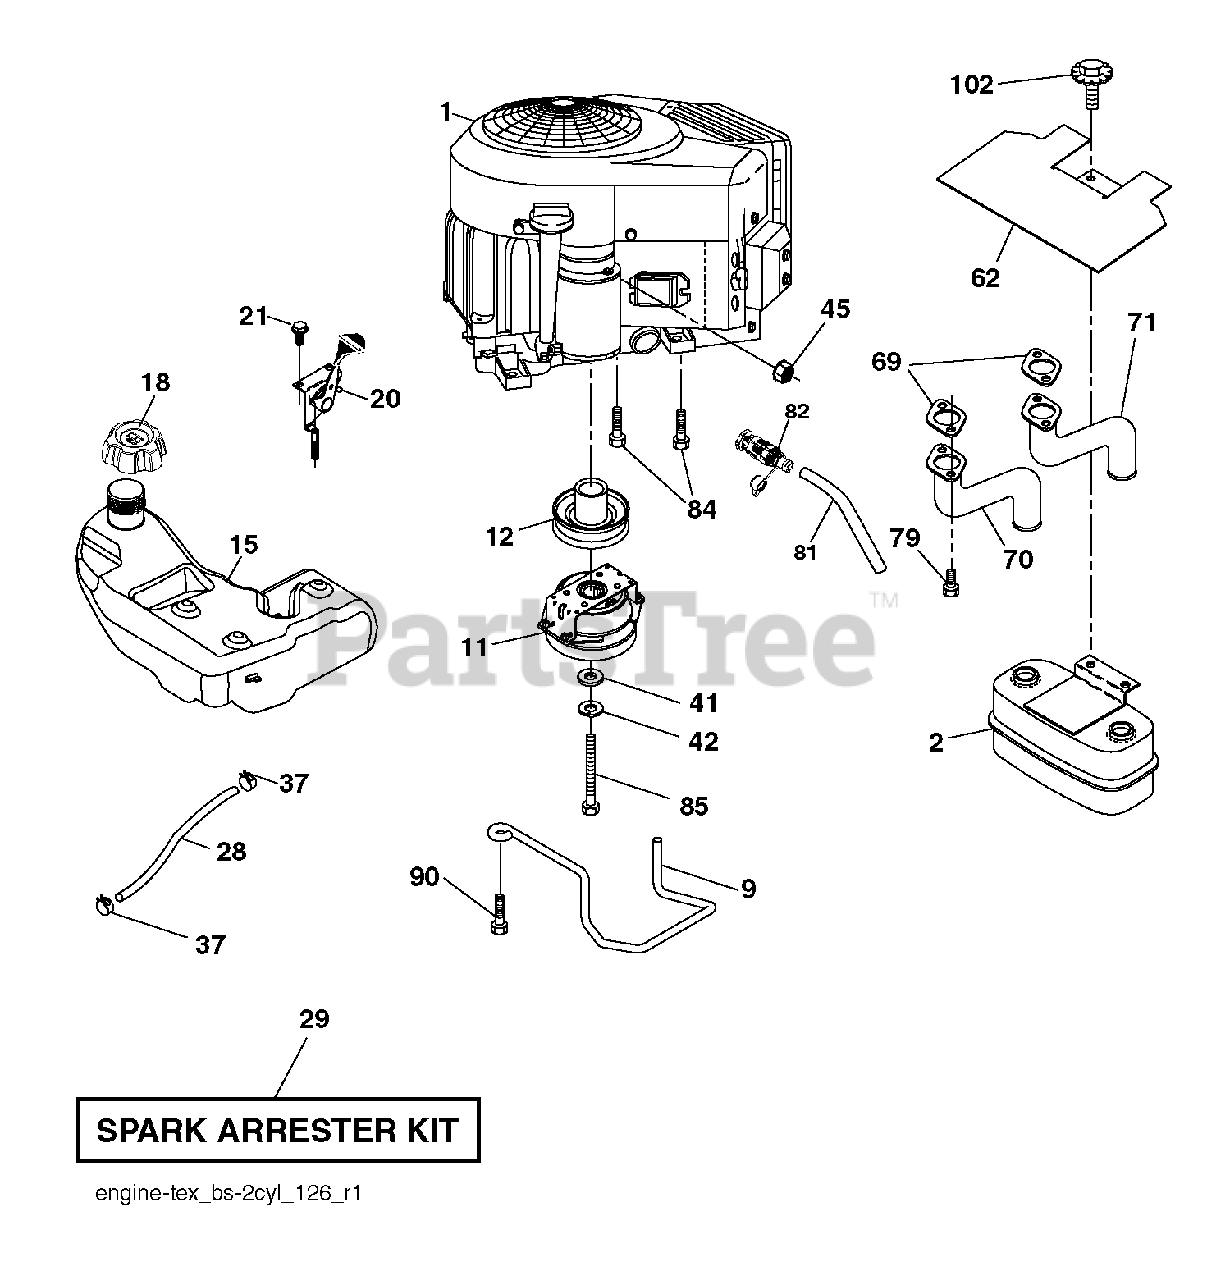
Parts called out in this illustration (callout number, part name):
2	MUFFLER.ASM.TWN.EXTNDED.DFLCTR
9	KEEPER.BELT.ENGINE
11	CLUTCH.OGURA.5.0PD.GT1.5A-EH07
12	PULLEY.ENGINE.ENX
15	TANK.ASSY.3.GAL.EPA
18	CAP ASSY FUEL 3" GRAY
20	THROTTLE.COBRA.38"READSTART.BK
21	SCREW.#10 X 0.750.BOS
28	LINE.FUEL.64"REAR.EMIS
29	KIT.SPARK ARRESTOR 794945 B&S
37	HOSE CLAMP
42	LOCKWASHER
45	NUT
62	SHIELD.HEAT.MUFFLER
69	GASKET.MUFFLER
70	EXHAUST.TUBE.LH.BS/TWIN
71	EXHAUST.TUBE.RH.B&S.TWIN.INTEK
79	SCREW.SOCKET.HEAD.5/16-18
81	TUBE, DRAIN OIL ASM.
82	VALUE.OIL.DRAIN
84	SCREW.3/8-16
85	BOLT HEX 7/16-20 X 3.75 GR. 5
90	SCREW 3/8-16X1
102	SCREW
